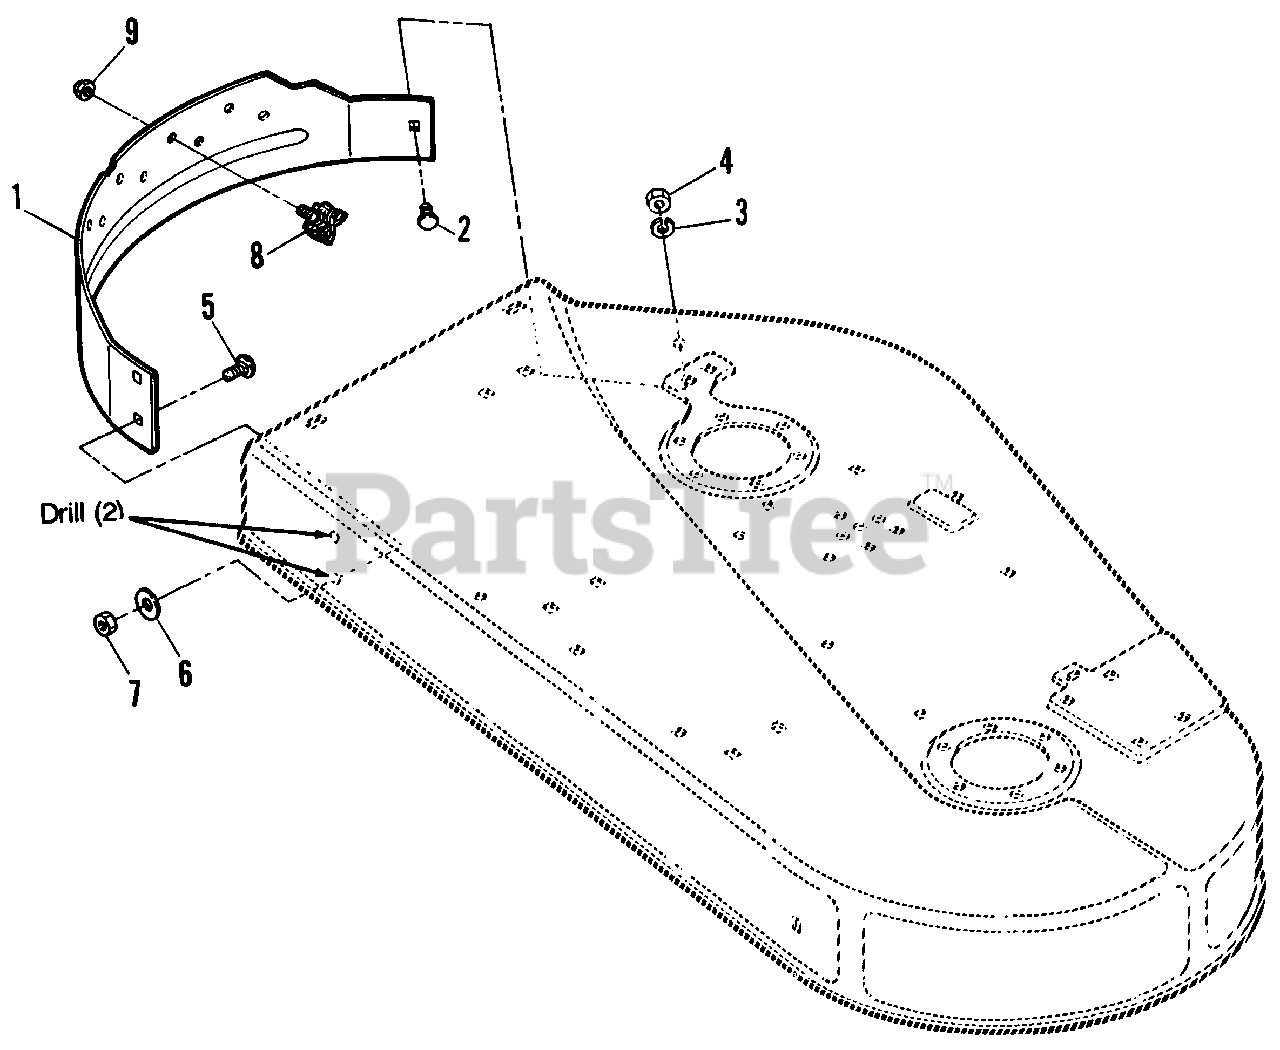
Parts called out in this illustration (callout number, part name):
1	BAFFLE, Discharge
2	CARRIAGE BOLT, 1/4-20 x 3/4"
3	LOCKWASHER, 1/4
4	NUT, Hex, 1/4-20
5	CARRIAGE BOLT, 5/16-18 x 3/4"
6	LOCKWASHER, 5/16
7	NUT, Hex, 5/16-18
8	SHREDDERS, Leaf
9	NUT, Hex, Plastite, 5/16-18
